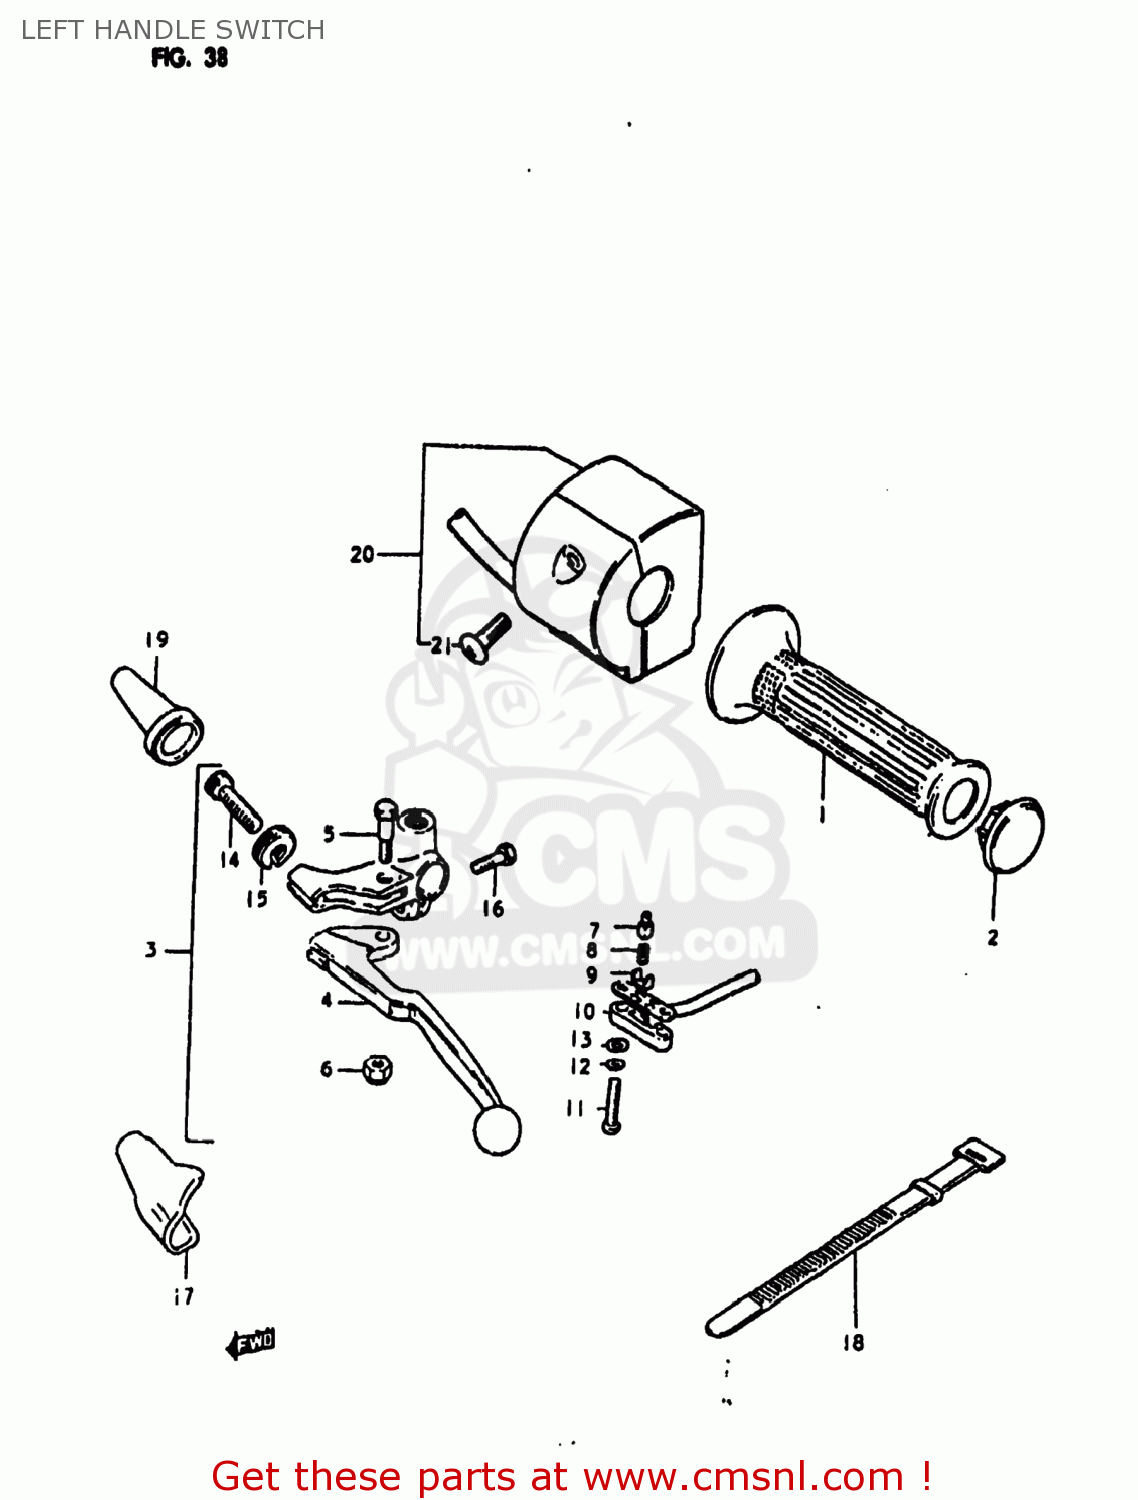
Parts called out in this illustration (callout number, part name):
1	GRIP,LEFT
2	CAP,GRIP END
3	LEVER ASSEMBLY
4	LEVER,CLUTCH
5	BOLT,LEVER
6	NUT 6MM
7	HOLDER
8	SPRING
9	PLATE
10	COVER,FR BK TERMINAL BASE
11	SCREW
12	LOCK WASHER
13	WASHER
14	ADJUSTER,CABLE
15	NUT,CABLE ADJUSTER
16	BOLT,CLUTCH LEVER HOLDER
17	COVER,CLUTCH LEVER
18	CLAMP(L:120)
19	BOOT,CLUTCH CABLE
20	SWITCH ASSEMBLY,HANDLE,LEFT
21	SCREW
